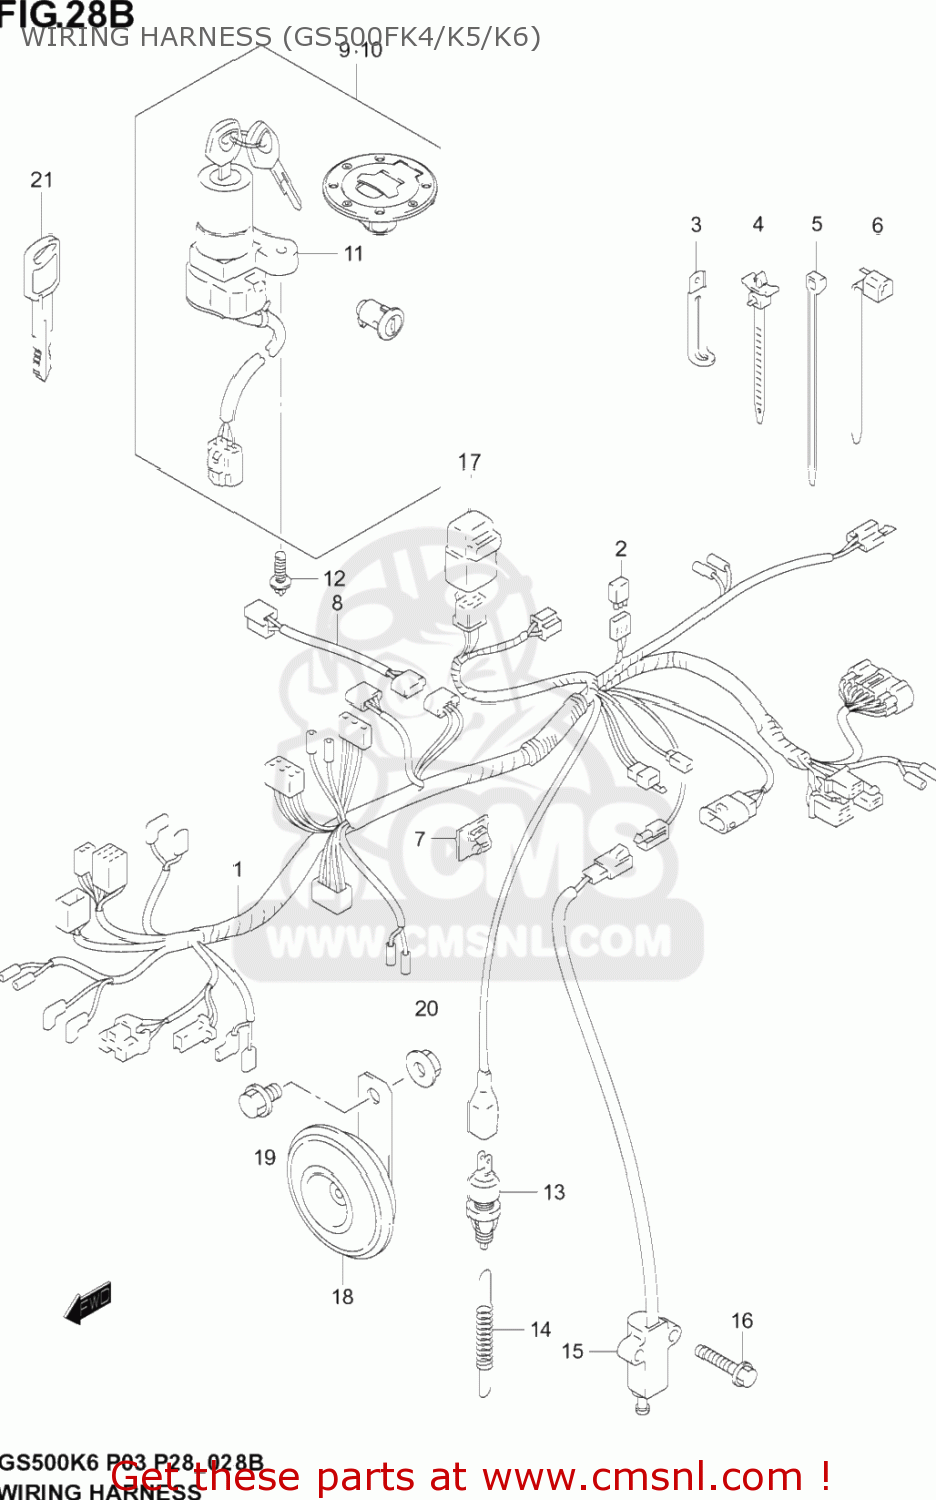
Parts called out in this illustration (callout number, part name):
1	HARNESS,WIRING
2	DIODE
3	CLAMP(L:45)
4	CLAMP
5	CLAMP
6	CLAMP(L:235)
7	CLAMP
8	WIRE,AIR SOLENOID
9	LOCK SET
10	LOCK SET
11	LOCK ASSY,STEERING
12	SCREW(6X18)
13	SWITCH ASSY,STOP LAMP
14	SPRING
15	SWITCH ASSY,SI
16	BOLT
17	RELAY ASSEMBLY
18	HORN ASSY
19	BOLT OIL DRAIN
20	BOLT
21	KEY,BLANK
